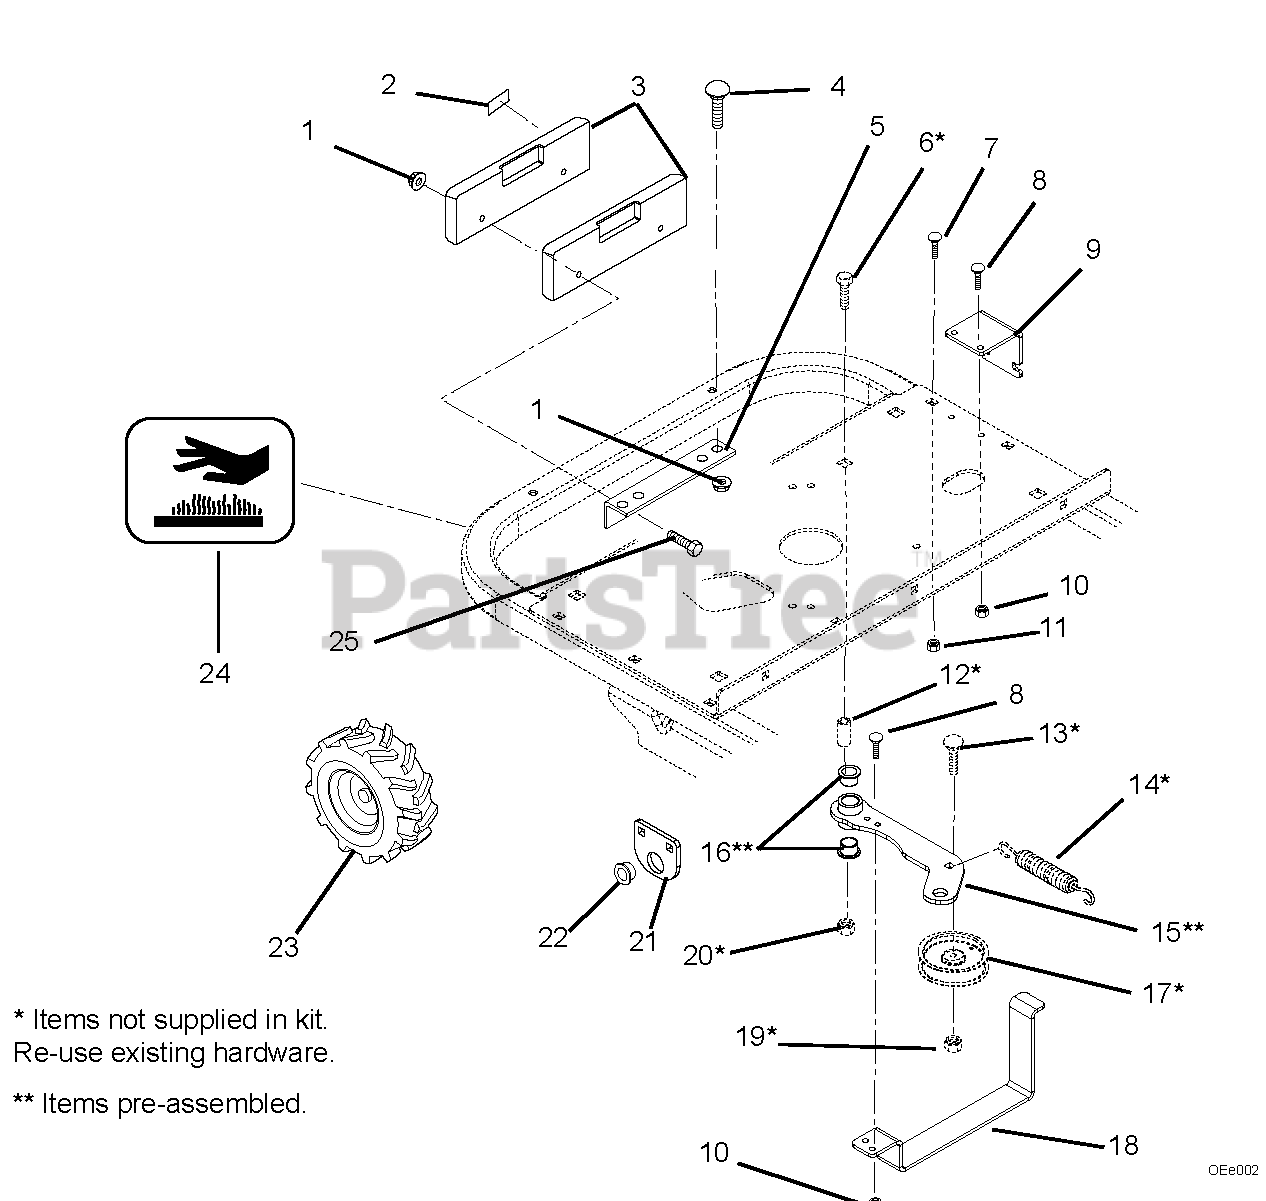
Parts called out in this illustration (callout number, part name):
1	Top Locking Flange Nut, .38-16
2	Reflector
3	Weight, Cast Iron
4	Bolt, Round Head Square Neck, .38-16 x 2.50 Grade 5
5	Angle Bracket
6	Bolt, Hex .50-13 x 2.50 Grade 5
7	Bolt, Round Head Square Neck .38-16 x 2.00
8	Bolt, Hex .25-20 x .75 Grade 5
9	Latch, Cold Start
10	Nut, Locking Top Flange .25-20
11	Nut, Locking Jam Center .375-16
12	Bushing Sleeve .50 x .75 x 1.56
13	Bolt, Round Head Square Neck .38-16 x 1.25 Grade 5
14	Spring, Extension
15	Weldment, Idler
16	Bushing, Flanged 0.75 x 0.875 x .625 x 1.125
17	Pulley, Idler 4.00
18	Handle, Cold Start
19	Nut, Locking, Jam, Center .375-16
20	Nut, Locking Top Flange .50-13
21	Bracket, Rear Pivot
22	Bushing, Flange 1 x 1.12 .62 1.50
23	Tire/Wheel Assembly, 18 x 6.5
24	Decal, Hot Surface
25	Bolt, Hex .38-16 x 4.50
